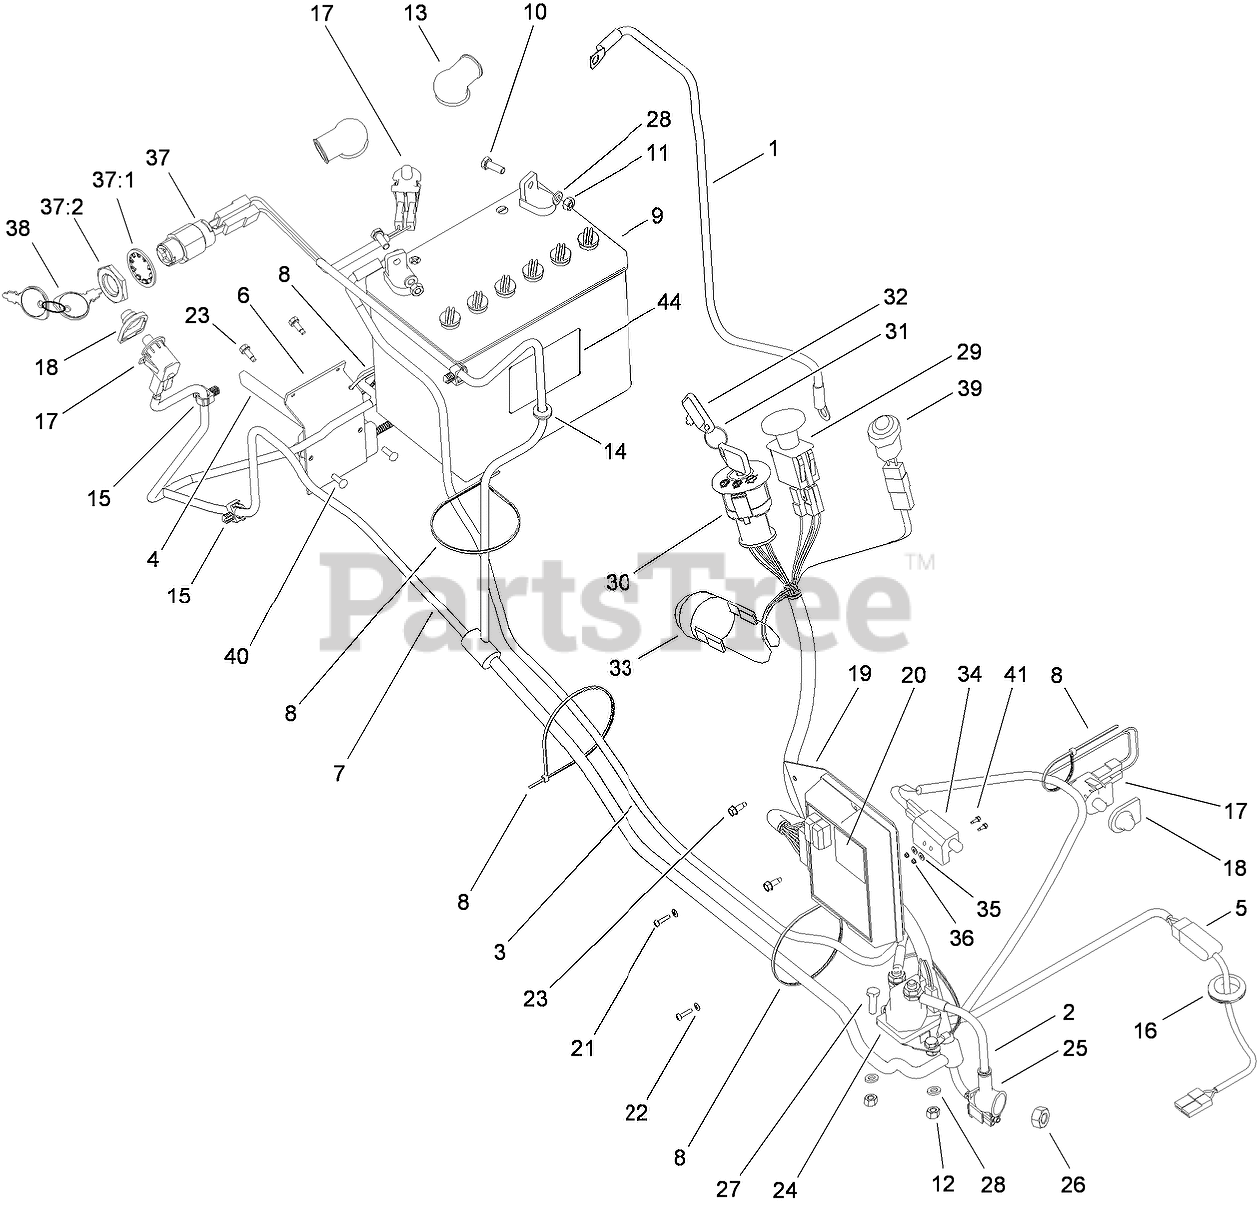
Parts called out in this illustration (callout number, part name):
1	CABLE-BATTERY, NEGATIVE
2	LEAD-STARTER, ELECTRIC
3	CABLE-BATTERY, POSITIVE
4	SWITCH-OMRON
5	HARNESS-CLUTCH
6	BRACKET-SWITCH
7	HARNESS-WIRING
8	TIE-CABLE
9	BATTERY
10	SCREW-HH
11	NUT-HEX
12	NUT-LOCK
13	BOOT-RUBBER
14	BUSHING
15	CLIP-SNAP
16	BUSHING
17	SWITCH-DELTA
18	COVER-PROTECTIVE
19	BRACKET-SUPPORT, MODULE
20	MODULE-CONTROL
22	WASHER
23	SCREW-TAP
24	Solenoid
25	BOOT-RUBBER
26	NUT-HHF
27	SCREW-HH
28	WASHER
29	SWITCH-PTO
30	SWITCH-IGNITION
32	KEY-IGNITION
33	BUZZER
34	SWITCH-DELTA
35	WASHER
36	NUT-HEX
37	STARTER SWITCH ASM
37:1	WASHER-TOOTH, INTERNAL
37:2	NUT-HH
38	KEY-IGNITION
39	LAMP-INDICATOR
40	Screw
44	DECAL-DANGER
